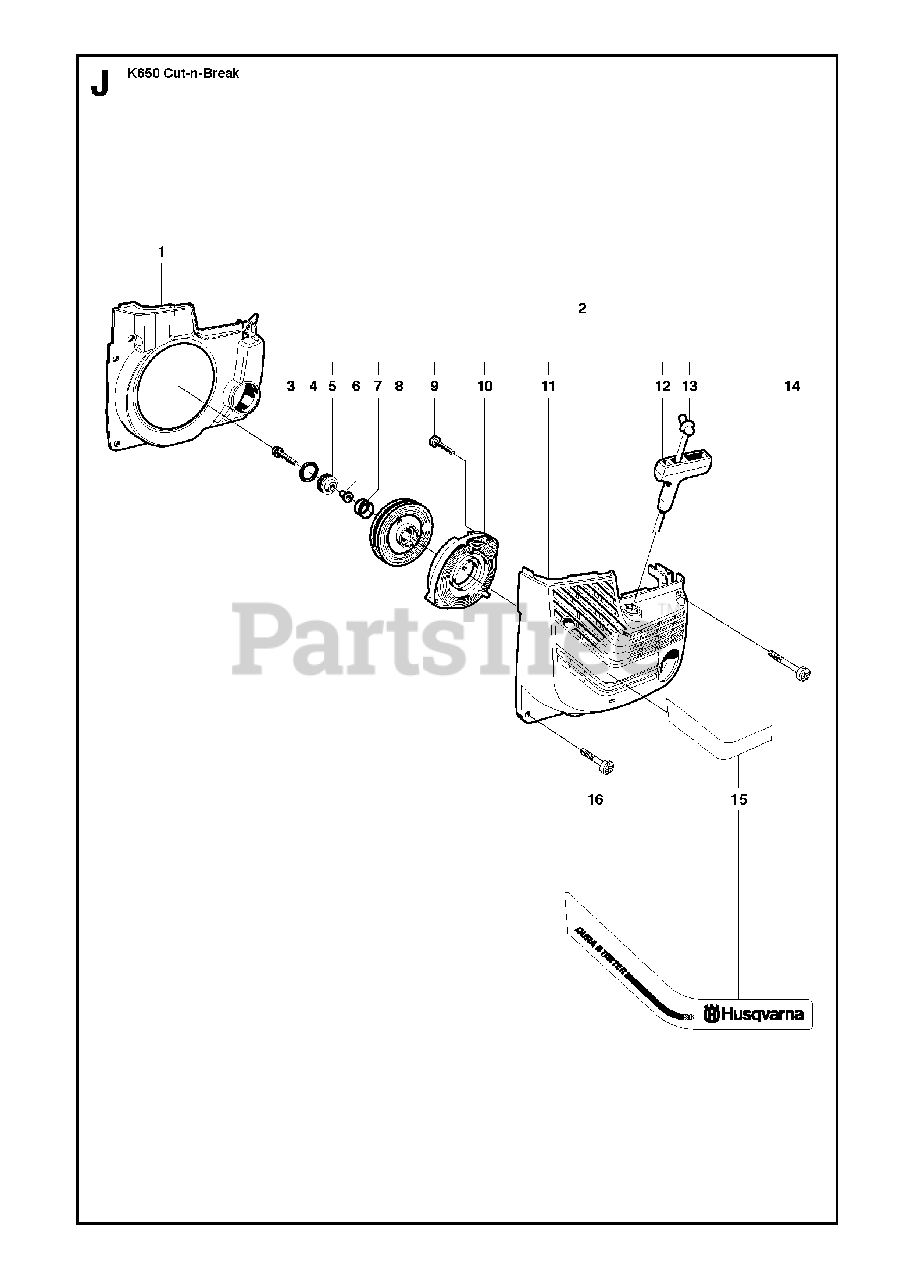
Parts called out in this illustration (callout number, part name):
3	SCREW IHSCFT
5	GROMMET
6	SPACING SLEEVE
7	COMPRESSION SPRING
8	STARTER PULLEY
9	SCREW CCRPANT
10	RECOIL SPRING
12	STARTER HANDLE
14	SCREW CCRPANMO
16	SCREW CCRPANMO
